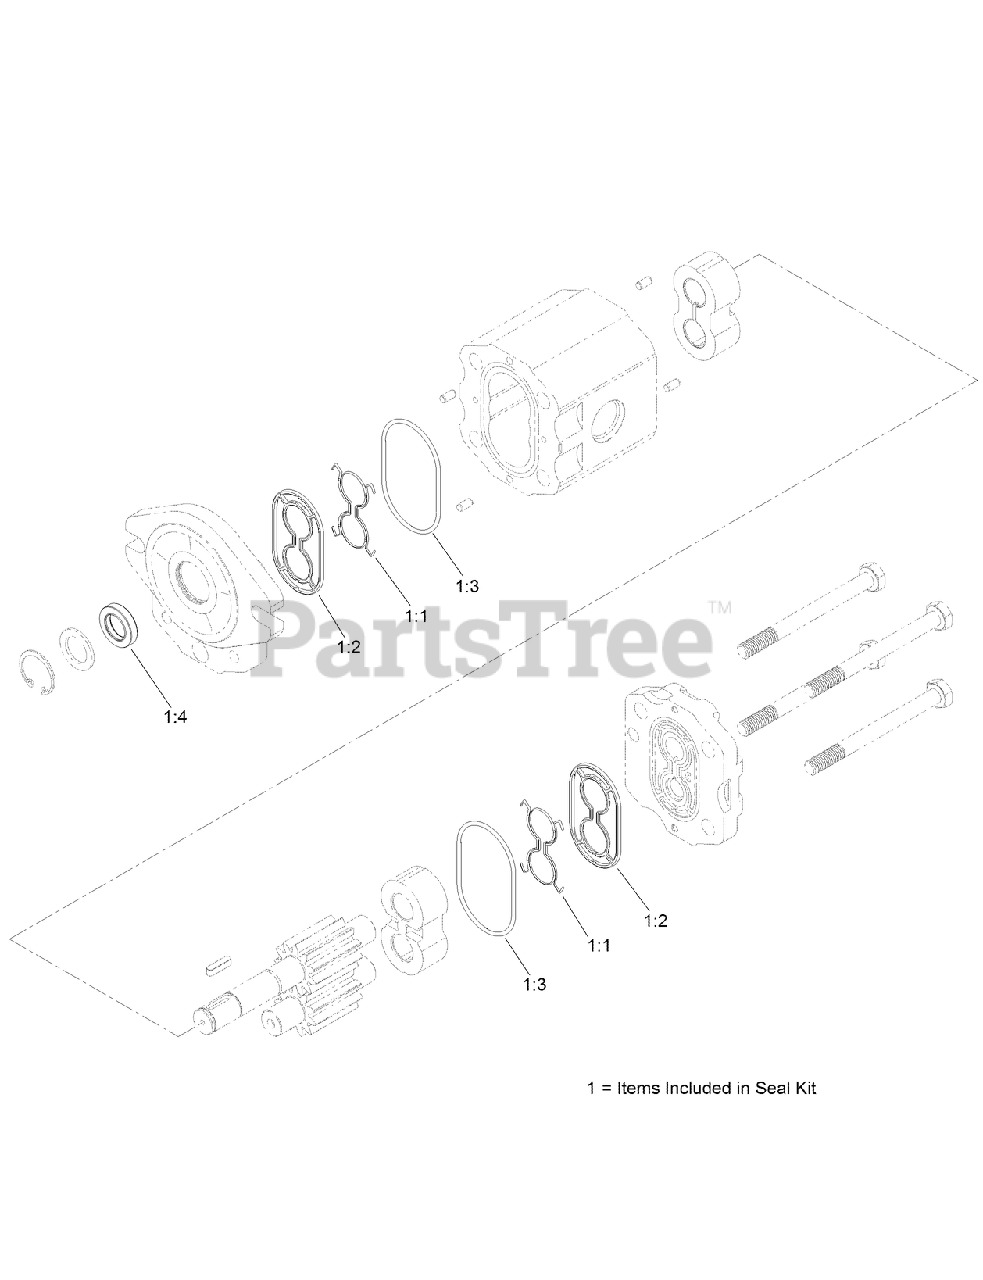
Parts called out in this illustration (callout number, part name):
1	SEAL KIT
1:1	SEAL
1:2	Seal-Pressure
1:3	O-RING
1:4	Seal-Lip, Shaft
